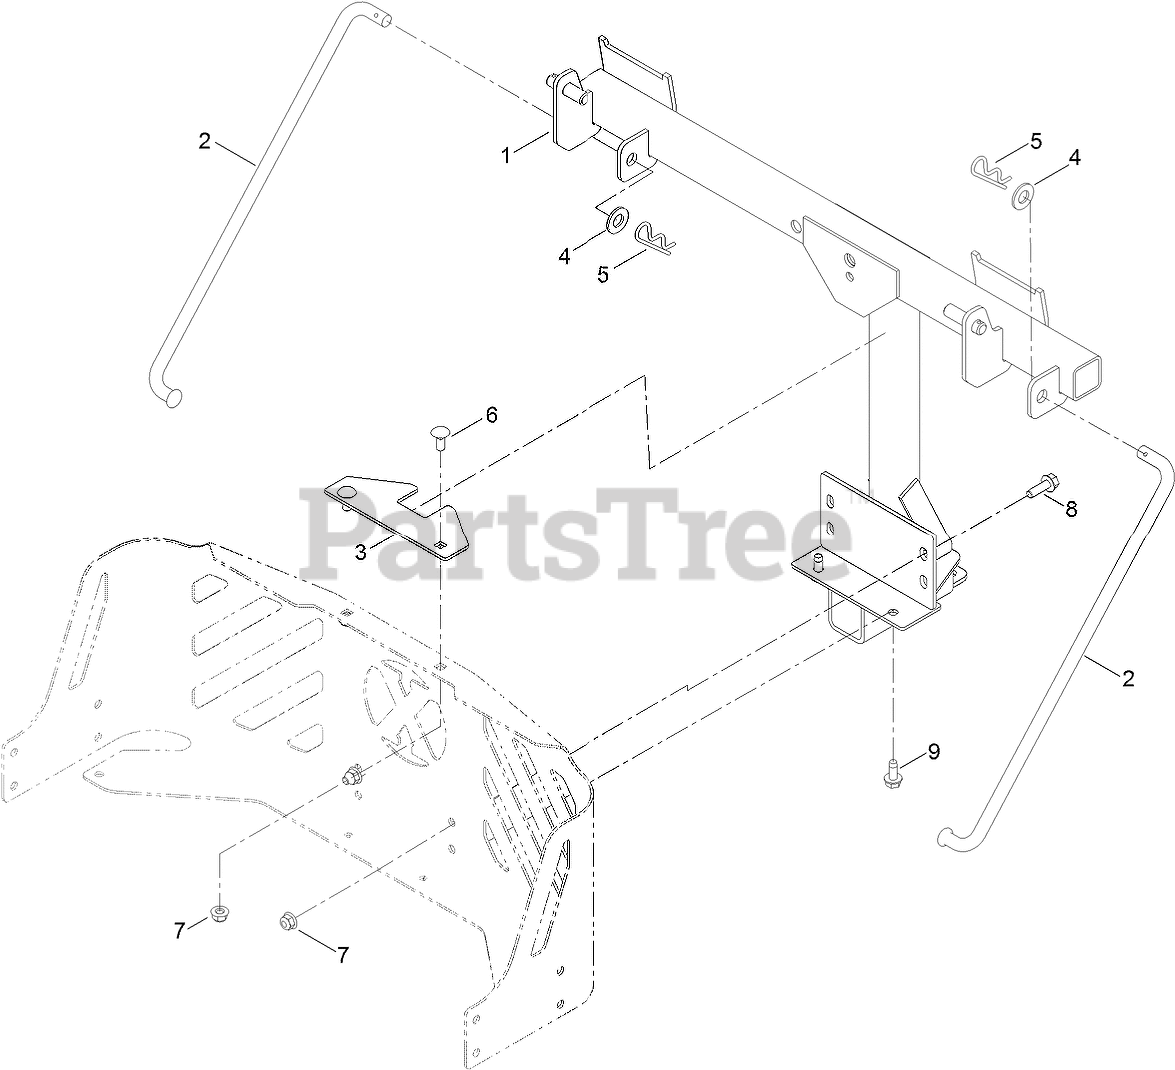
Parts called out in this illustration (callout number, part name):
1	FRAME-PIVOT
2	ROD-SUPPORT
3	BRACKET-STABILIZER
4	WASHER-FLAT
5	PIN-HAIR
6	BOLT-CARR
7	NUT-HF, NI
8	SCREW-HHF
9	SCREW-HWHTF
